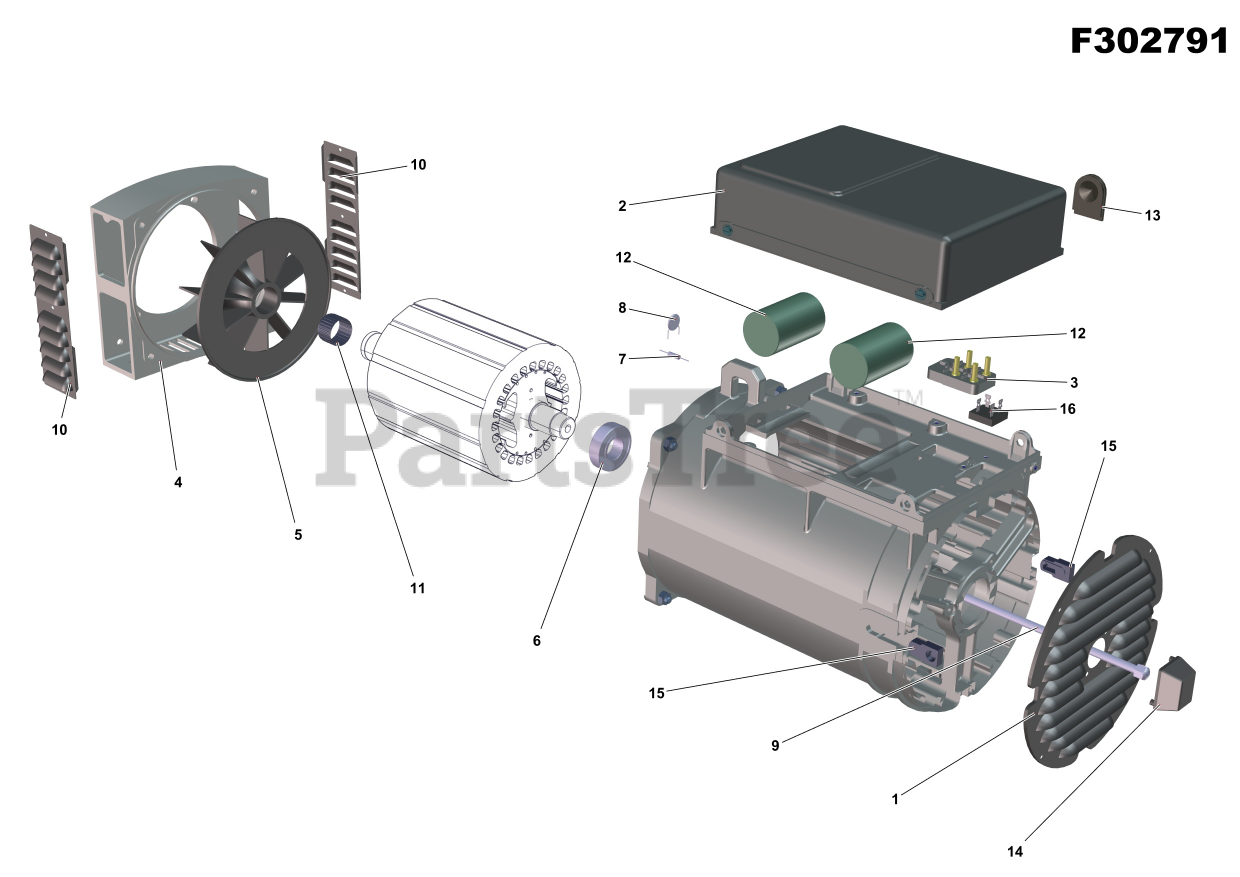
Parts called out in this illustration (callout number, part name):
3	Terminal board
4	Front flange
7	DIODE D2/125 25A
9	Securing stud
10	Protection grid
12	CAPACITOR
15	Rubber Plug
16	Diods bridge
